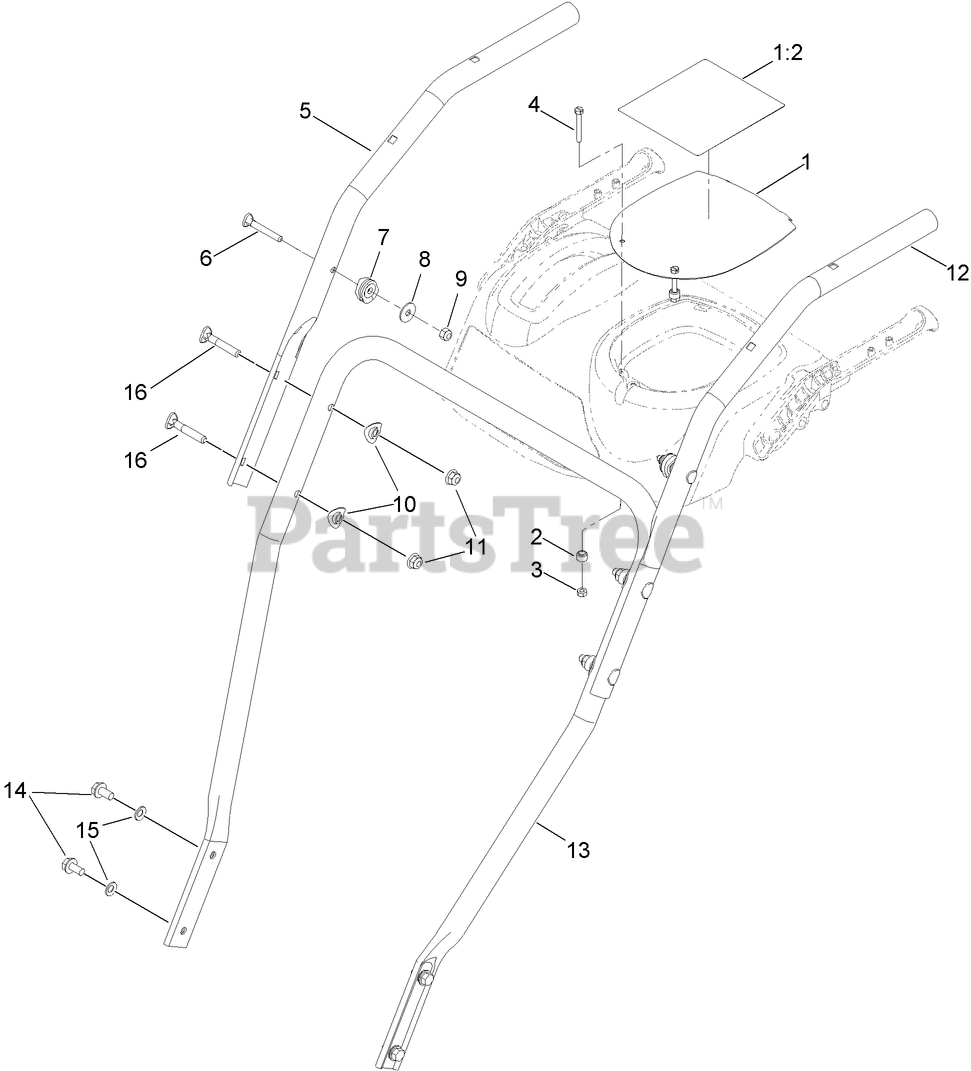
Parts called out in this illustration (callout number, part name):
1	PANEL-CONTROL
1:2	DECAL-WARNING
2	SPACER-BLADE, ROTOR
3	NUT-LOCK, NI
4	SCREW
5	HANDLE-UPPER, RH
6	SCREW
7	CLAMP-CABLE
8	WASHER-PLAIN
9	NUT-LOCK, NI
10	WASHER
11	NUT-HF, NI
12	HANDLE-UPPER, LH
13	HANDLE-LOWER
14	SCREW-HWHTF
15	WASHER-BELLEVILLE
16	SCREW-HANDLE
